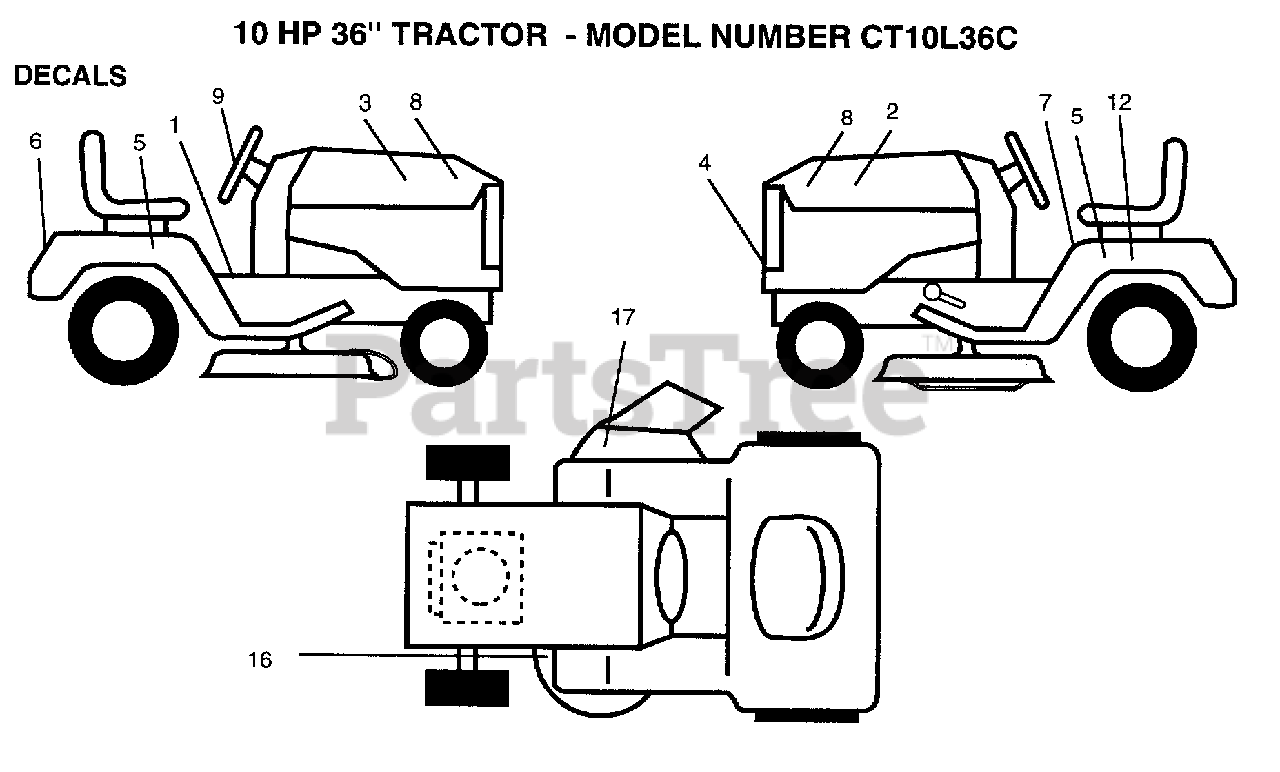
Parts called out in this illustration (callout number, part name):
1	DECAL.INST.OPER
2	DECAL HD RLY LH
3	DECAL HD RLY RH
4	GRILL DECAL
5	DECAL.FEND.QUICKS
6	FENDER DECAL
7	DECAL
9	"DECAL,STR WHL"
12	DECAL
16	"DECAL, WARNING"
17	DECAL.V.BELT
